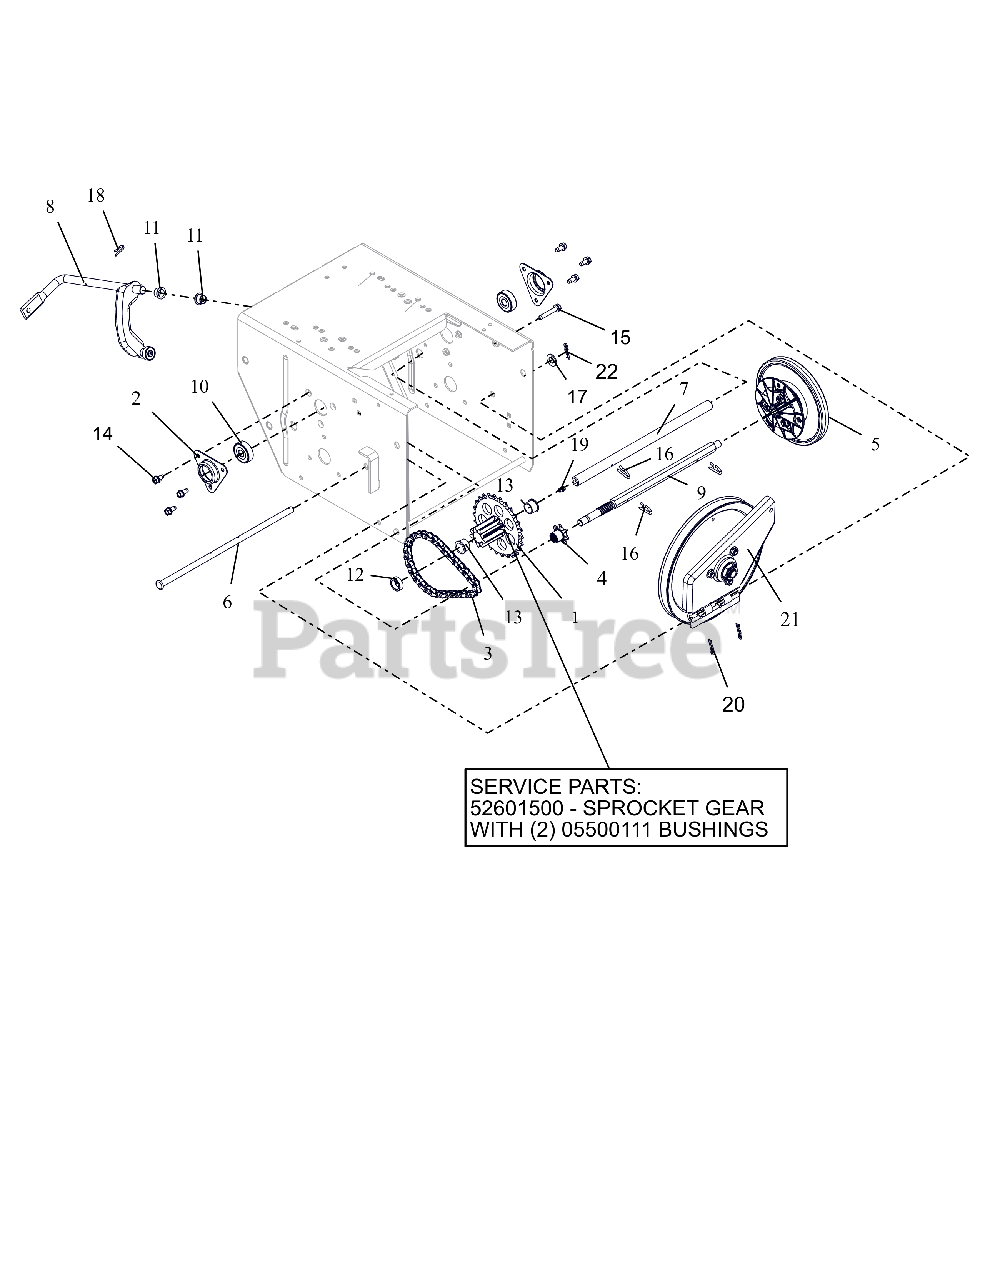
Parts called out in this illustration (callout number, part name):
1	PINION & SPROCKET
1	PINION & SPROCKET W/BUSHINGS
2	FLANGE, BEARING
3	CHAIN - #41, 32 PITCHES
4	SPROCKET, PINION 7T W/SPLINE
5	DISC, FRICTION DRIVE-ASSEMBLY
6	PIN, PIVOT
7	SHAFT, PINION
8	ARM, SHIFT - ASSEMBLY
9	SHAFT, HEX - HEAT TREATED
10	BRG-BALL .437X1.375X.437
11	BUSHING, POLYLINER-.50 SPLIT
12	BSHG-SLV, .635X.880X.305
13	BSHG-FLG .625X.750X.500X.875
14	SCR-TAP .25-20X.50 HWH ZCC
15	SCR,TAP .25-20X1.50 HWH TR ZCC
16	PIN, SPRING CLIP
17	WSHR,FLT .406X.812X.065 ZCC
18	CLIP, SPRING
19	ZERK,FITTING .25X.125 DRIVE IN
20	PIN, HAIR #225 .072X1.09
21	PLATE, SWING ASSEMBLY-DEEP
22	PIN, HAIR #225 .072X1.09
